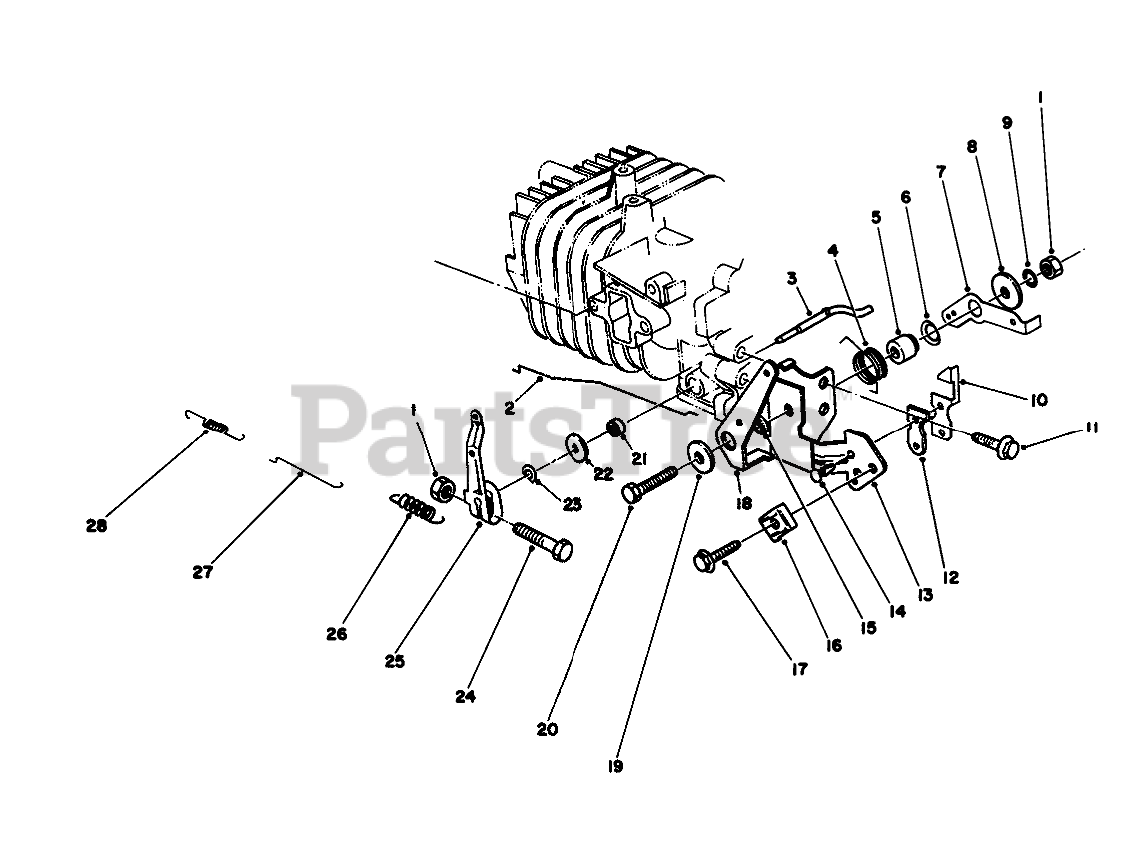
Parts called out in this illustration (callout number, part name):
2	CHOKE ROD
3	Shaft-Govemor
4	SPRING-CHOKE LEVER
5	Gov Lever Spacer
6	Washer-Gov. Spring Lever
7	GOV SPRING LEVER
8	WASHER
9	LOCKWASHER
10	TERMINAL-KILL SWITCH
12	INSULATOR-KILL SWITCH
13	BRACKET-THROTTLE, CONTROL
14	KILL SWITCH RIVET
15	SPACER-CHOKE LEVER
16	CLAMP
18	LEVER-CONTROL, CHOKE
19	WASHER
21	SEAL-OIL
22	WASHER
23	E-RING
25	Lever-Throttle Control
26	GOVERNOR SPRING
27	ROD-CARBURETOR
28	SPRING
